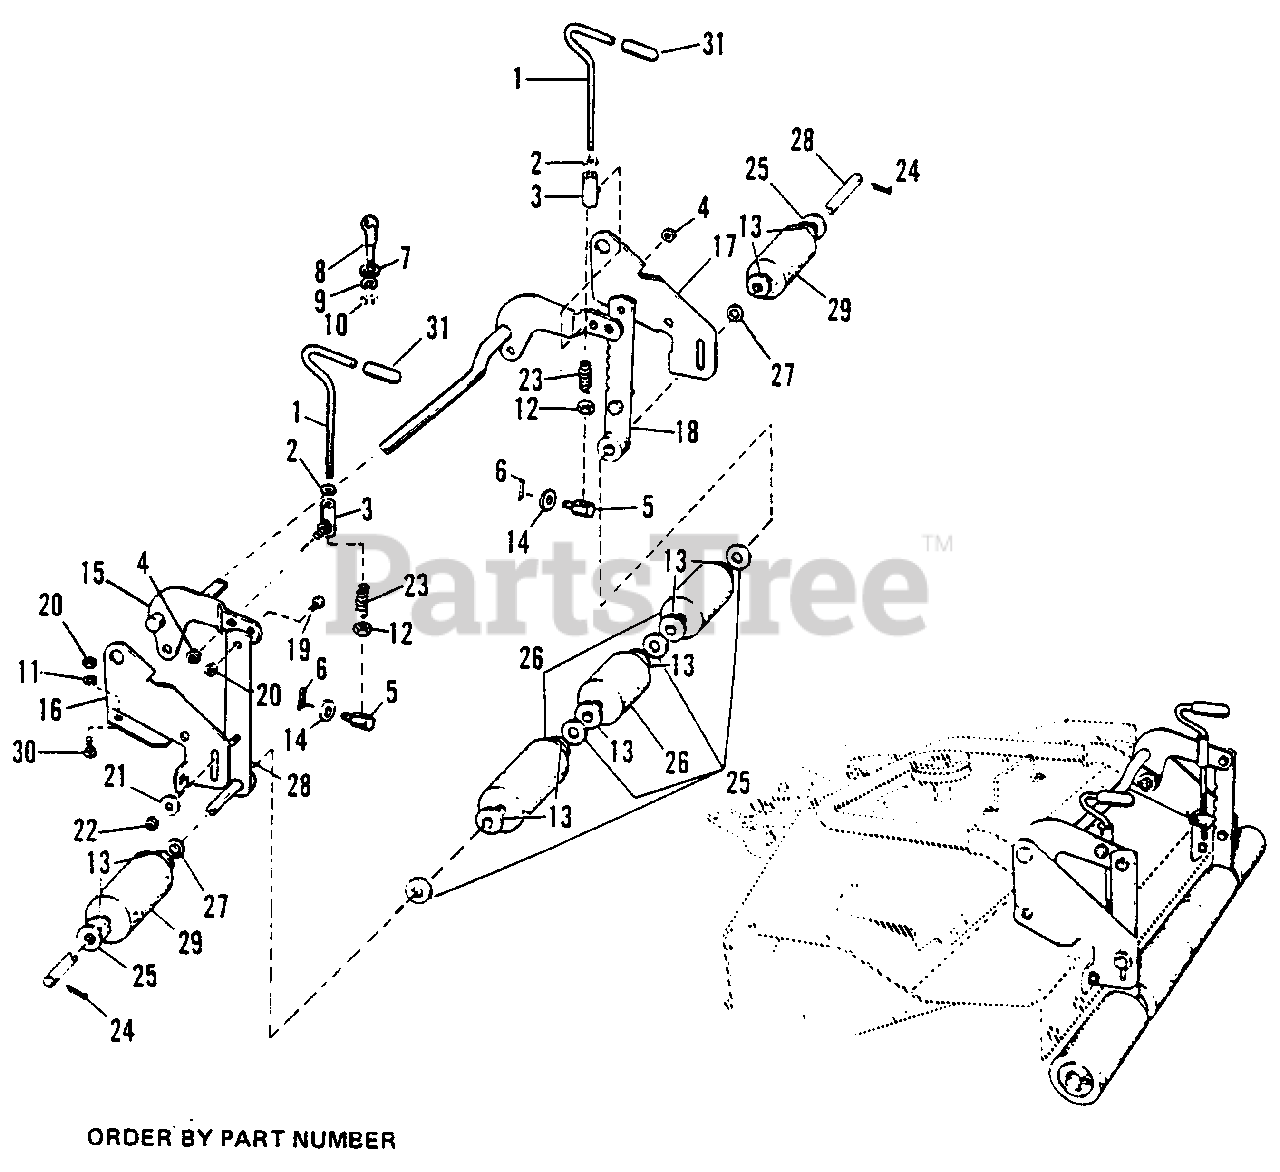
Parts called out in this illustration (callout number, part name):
1	Screw Assembly, Adjusting
2	Plain Washer, 3/8"
3	Socket Assembly, Crank
4	Full Lock Hex Nut, 3/8"-16
6	Cotter Pin, 3/32" x 3/4"
7	Plain Washer, 5/16"
9	Lockwasher, 3/8" Std.
10	Full Hex Nut, 3/8"-16 NC
11	Lockwasher, 3/8"
12	Full Hex Nut, 3/8"-16 NC
14	Plain Washer, 3/8" Std.
15	Arm Assembly, Rocker
16	Bracket, Roller, Right Hand
17	Bracket, Roller, Left Hand
18	Bar Assembly, Roller
19	Hex Capscrew, 3/8"-16 x 1"
20	Full Hex Nut, 3/8"-16 NC
21	Plain Washer, 3/8"
22	Full Lock Hex Nut, 3/8"-16
23	Spring, Adj. Screw
24	Cotter Pin, 3/16" x 1"
26	Roller w/Bushing
28	Shaft and Support Arm
29	Roller w/Bushing
30	Carriage Bolt, 3/8"-16 x 3/4"
